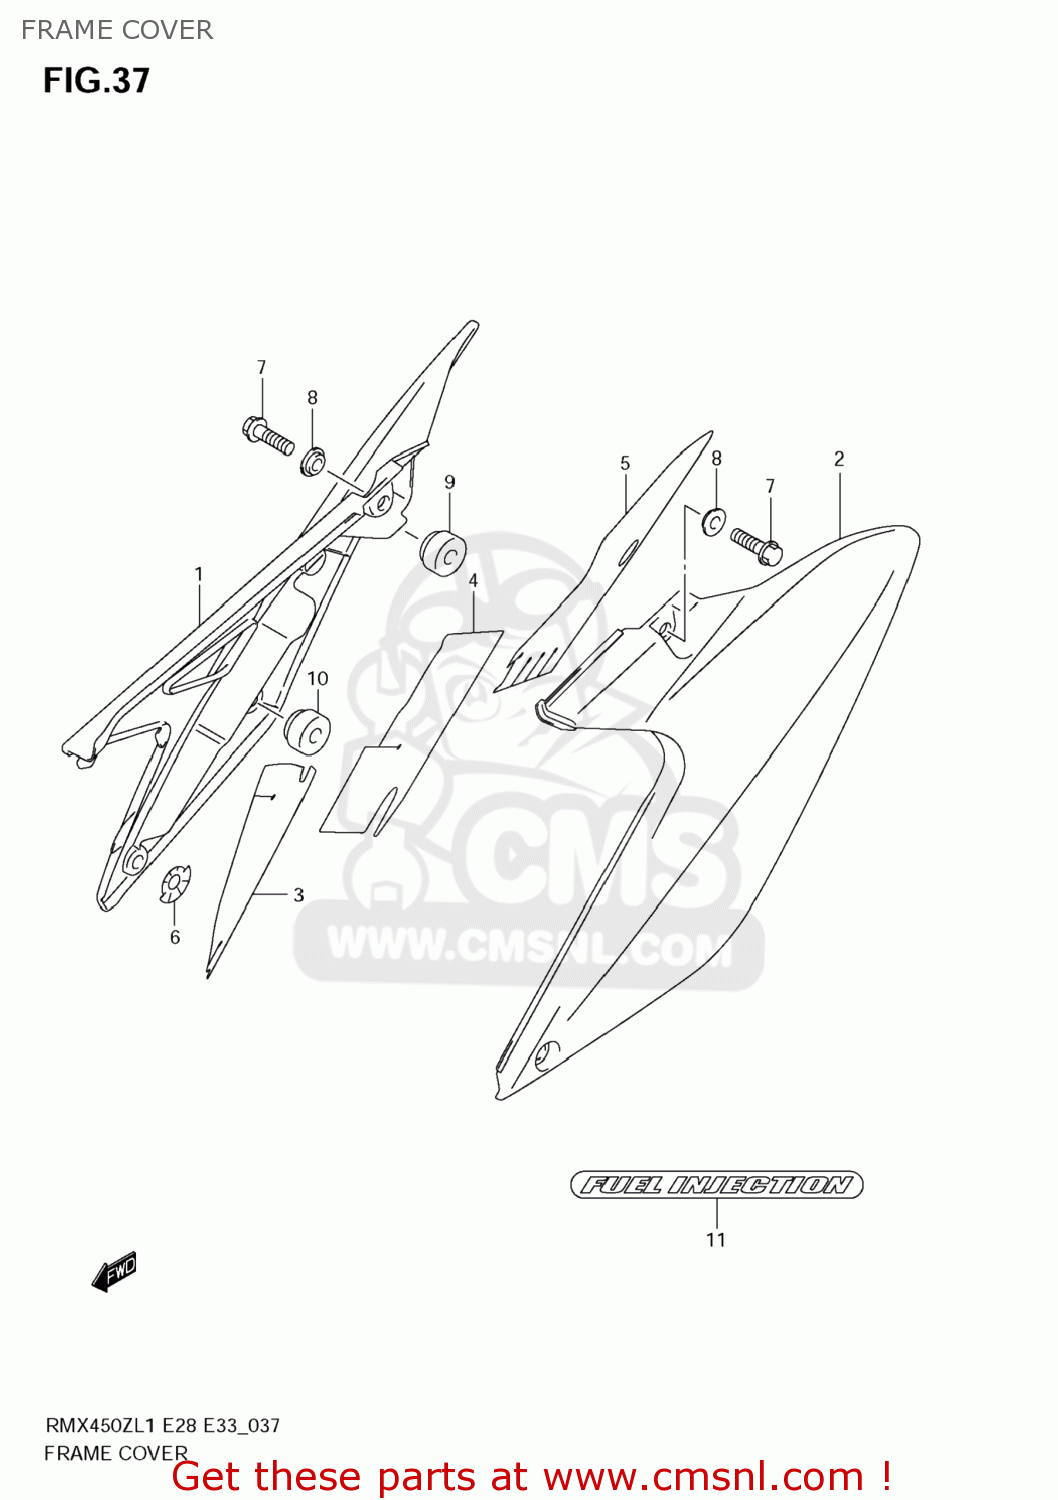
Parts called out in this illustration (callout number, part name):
1	COVER,FRAME,R(WHITE)
2	COVER,FRAME,L(WHITE)
3	SHIELD,FRAME COVER,R NO.1
4	SHIELD,FRAME COVER,R NO.2
5	SHIELD,FRAME COVER,R NO.3
6	SHIELD,FRAME COVER,R NO.4
7	BOLT
8	WASHER,FUEL TANK COVER
9	CUSHION
10	CUSHION
11	EMBLEM,FRAME COVER
